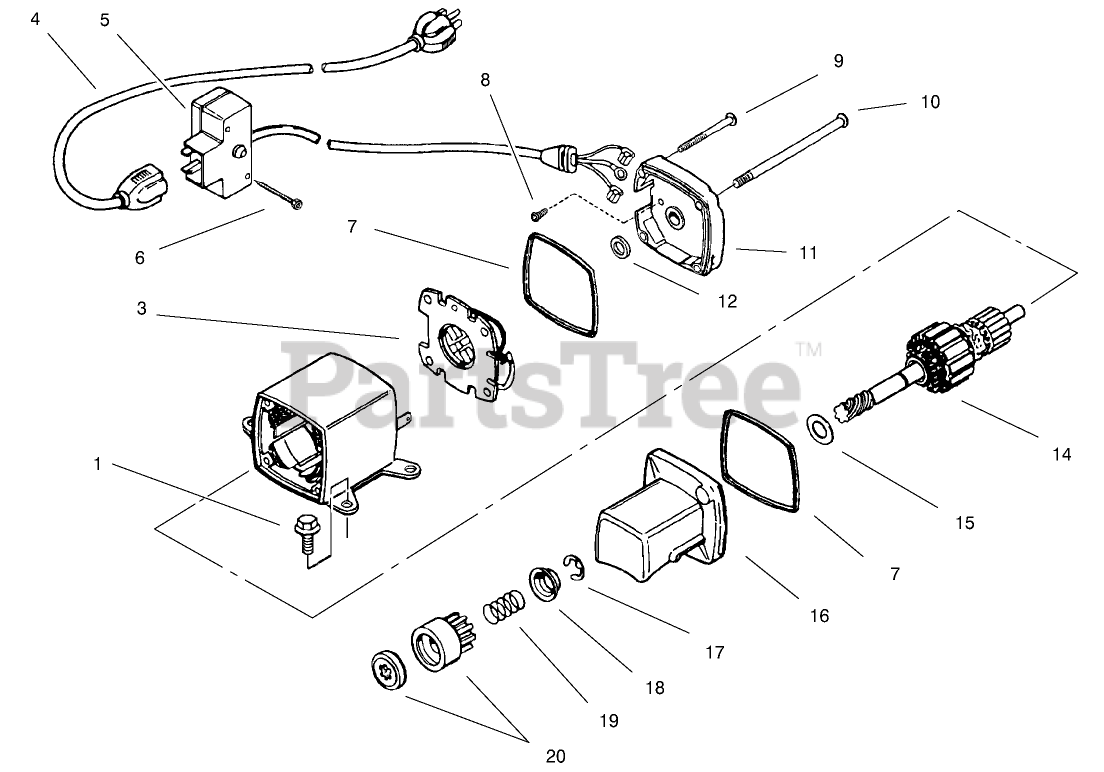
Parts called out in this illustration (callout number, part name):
1	Screw (T-30, 1/4-20 x 23/32)
3	Brush Card ASM
4	Cord-Extension (10-6)
5	Box Assembly-Switch (Incl. Ref. #26)
6	Screw
7	O-Ring
8	Screw-Ground
9	Screw-Ground
10	Bolt-Case
11	Cap Assembly (Incl. Ref. #7)
12	Washer-Thrust
14	Armature
15	Washer-Thrust
16	Cap Assembly (Incl. Ref. #7)
17	Retainer-Ring
18	Retainer-Spring
19	Spring-Anti Drift
20	Nut Gear
